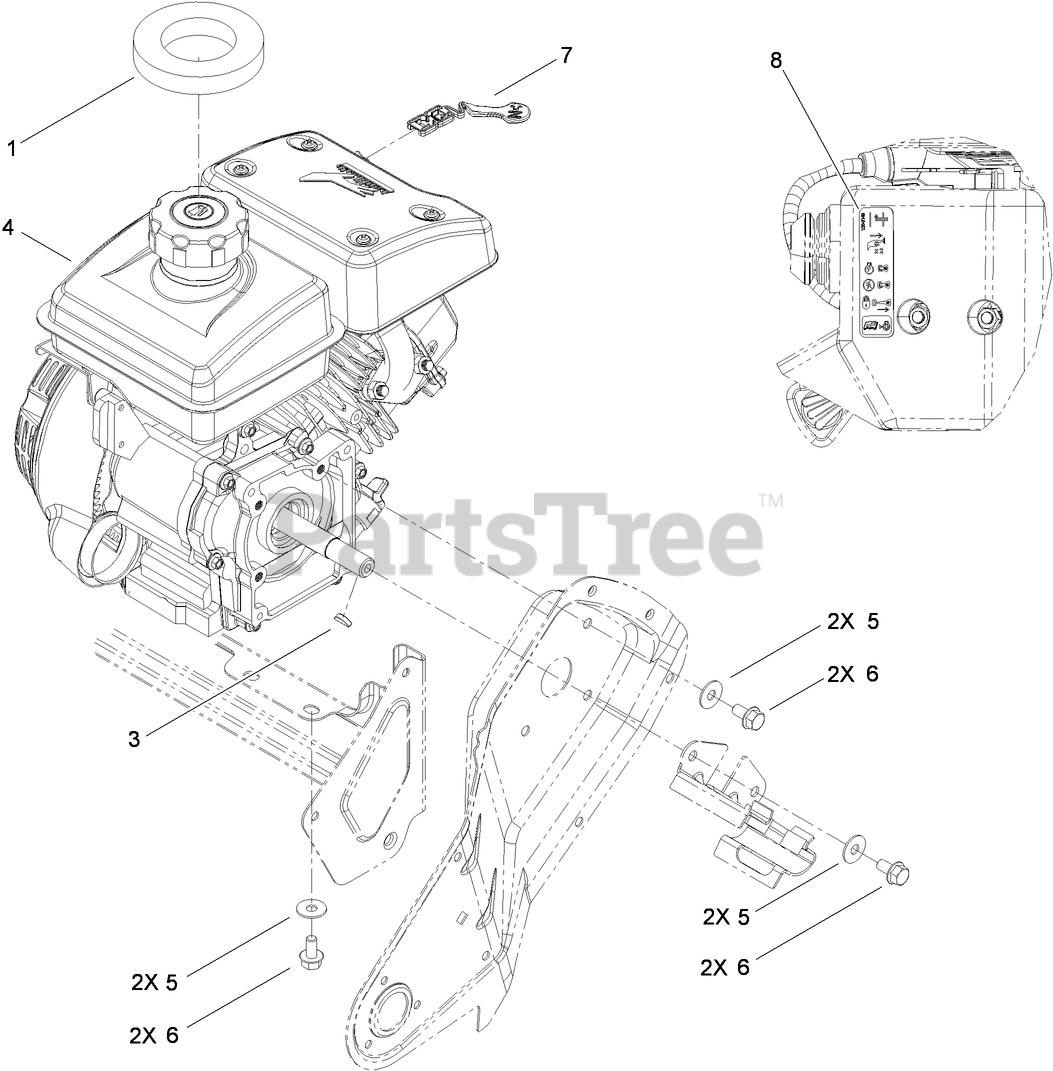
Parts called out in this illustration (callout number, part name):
1	SEAL-TANK
3	KEY-WOODRUFF
4	ENGINE-154FS-1
5	WASHER-BELLEVILLE
6	SCREW-HHF
7	LEVER-CHOKE
8	DECAL-CONTROLS, ENGINE
